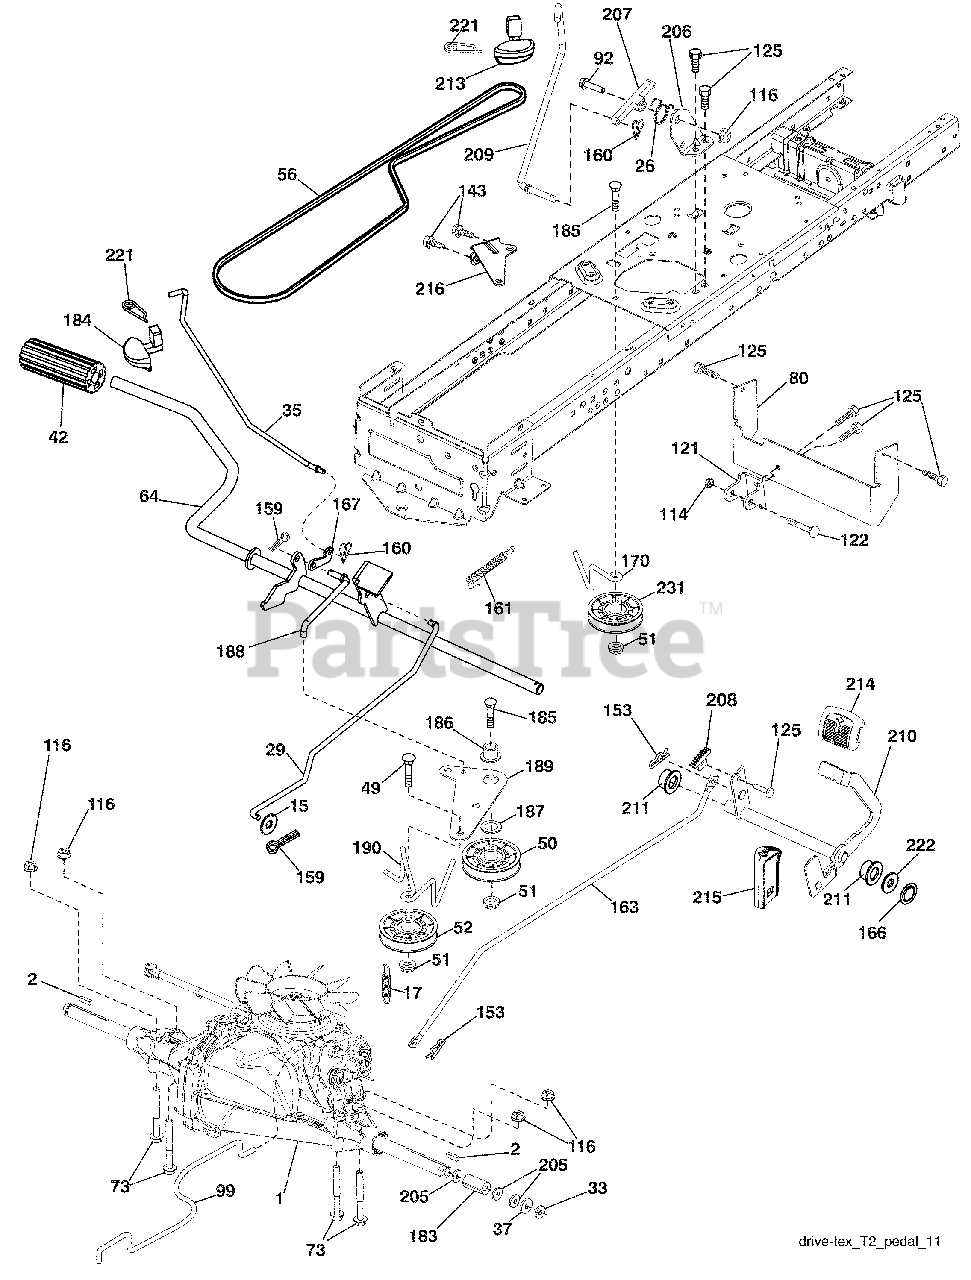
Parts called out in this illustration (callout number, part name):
2	Key Square
15	Washer 13/32 x 13/16 x 16 Ga.
17	Spring, Brake
26	Spring Return Cruise
29	Rod, Brake
35	Rod, Brake, Park
37	Washer 25/32 x 1-1/4 x 16 Ga.
42	Cover, Foot Pedal
50	Pulley Idler Flat
51	Lock Nut 3/8-16
52	Idler V-Groove 910" Offset
56	V-Belt, Drive
64	Shaft Asm. Pedal Brake Control
73	Bolt Hex 5/16-18 Gr. 5
80	Strap Torque
92	Bolt Fin Hex 5/16-18 unc x 1.25
99	Rod Spring Bypass
114	Nut Lock HX w/Ins 5/16-18
116	Nut Lock Hex Flange 5/16-18
121	Bracket Strap Torque
122	Bolt 5/16-18 x 2.50
125	Screw 5/16-18 x 3/4
143	Screw 5/16-18 x 1/2
153	Retainer Spring 1"
159	Pin Cotter 1/8 x 3/4
160	Retainer Clip
161	Spring, Return, Clutch
163	Rod Control
166	Nut Push
167	Latch Brake Parking
170	Keeper V-Idler
183	Spacer Axle
184	Handle Parking Brake
186	Spacer Retainer
187	Washer
188	Link Clutch Ground Drive
189	Bellcrank Ground Drive
190	Keeper Bellcrank Ground Drive
205	Washer 25/32 x 1-5/8 x 16 Ga.
206	Bracket Mount Latch Cruise
207	Latch Control Cruise
208	Gear Sector Control Cruise
209	Rod Control Cruise
210	Rocker Asm. Pedal Control
211	Bearing Nylon
213	Knob Control Cruise
214	Pedal Forward
215	Pedal Reverse
216	Bracket Pulley Idler
221	Retainer Spring Clip Handle
222	Washer 21/32 x 1-1/4 10 Ga.
231	Idler V-Groove 1.688" Offset
